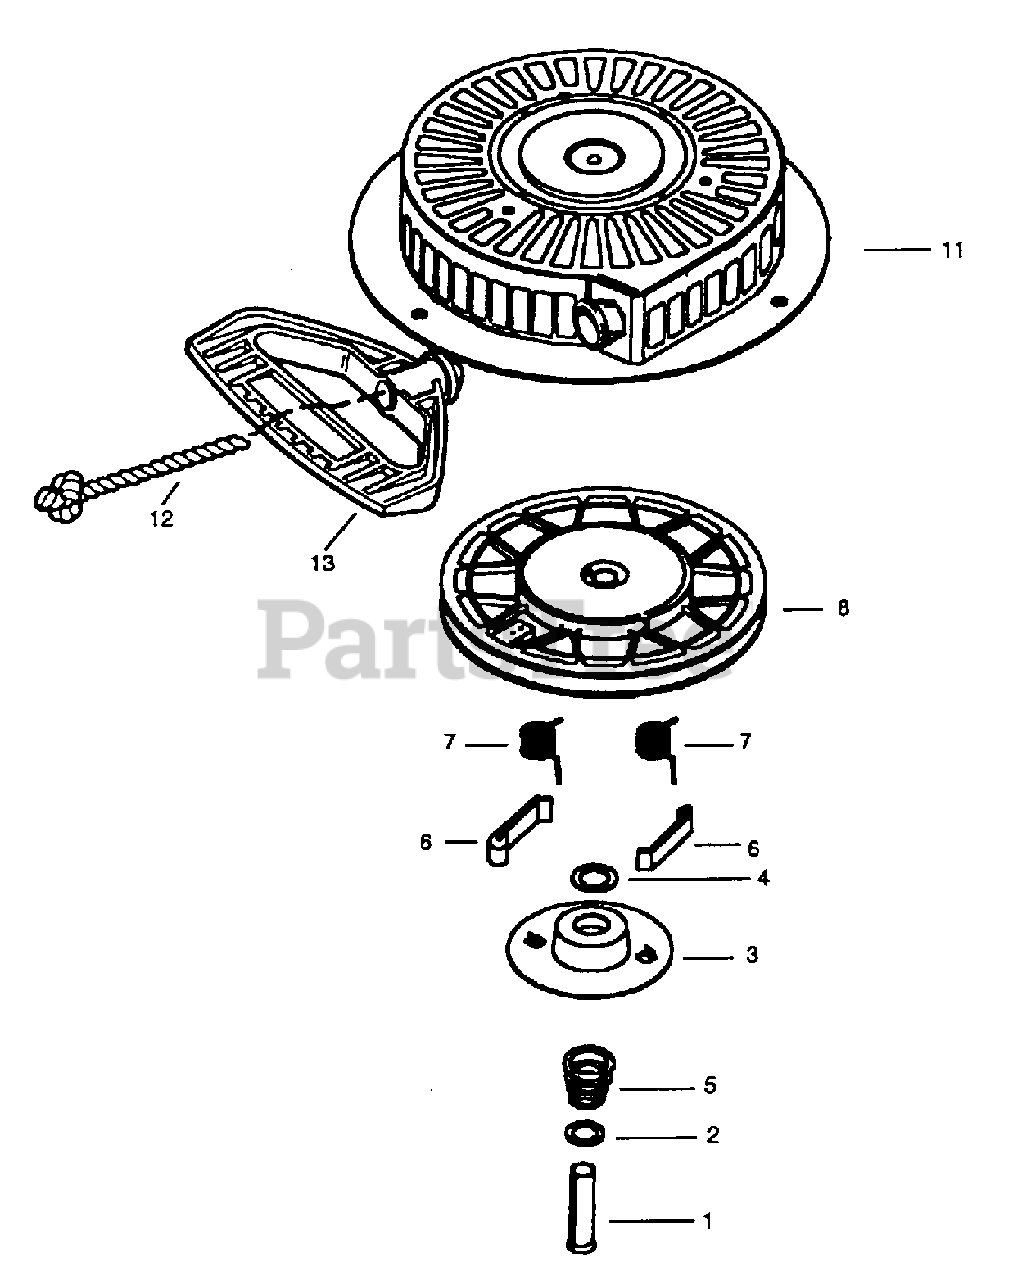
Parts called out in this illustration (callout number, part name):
1	Pin-Spring (Incl. Ref. #4)
2	Washer
3	Retainer
4	Washer
5	Spring-Brake
6	Dog-Starter
7	Spring-Dog
8	Pulley & RewindSpring Assembly
11	Starter Housing Asm
12	Rope-Starter
13	Handle-Mitten Grip
